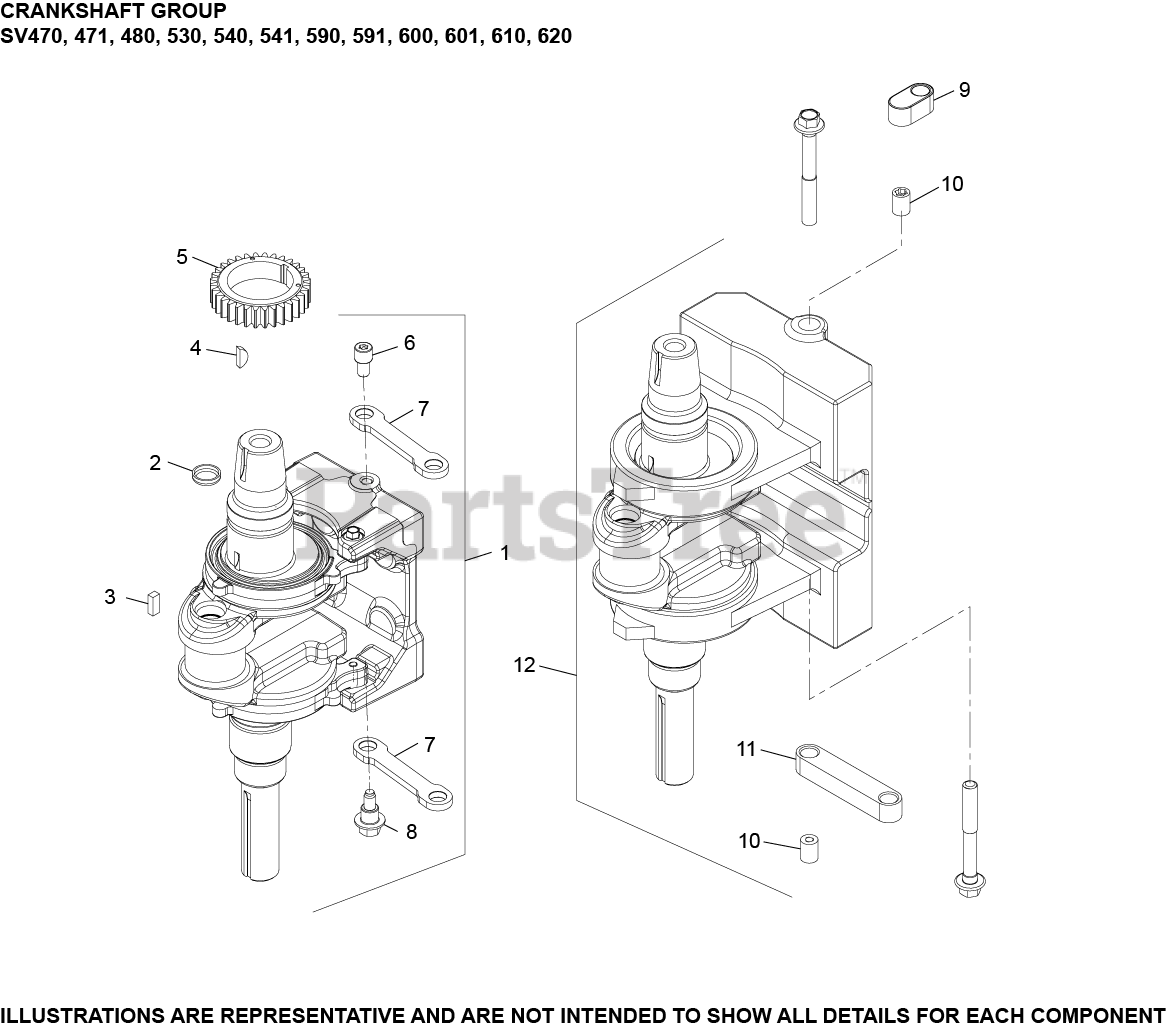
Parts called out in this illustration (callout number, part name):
1	CRANKSHAFT ASSEMBLY
2	PLUG, CUP
4	KEY, 3/16" X 5/8"
5	GEAR, CRANKSHAFT
6	SCREW, LINK PIVOT
7	LINKAGE, BALANCE WEIGHT
8	SCREW, SHOULDER
